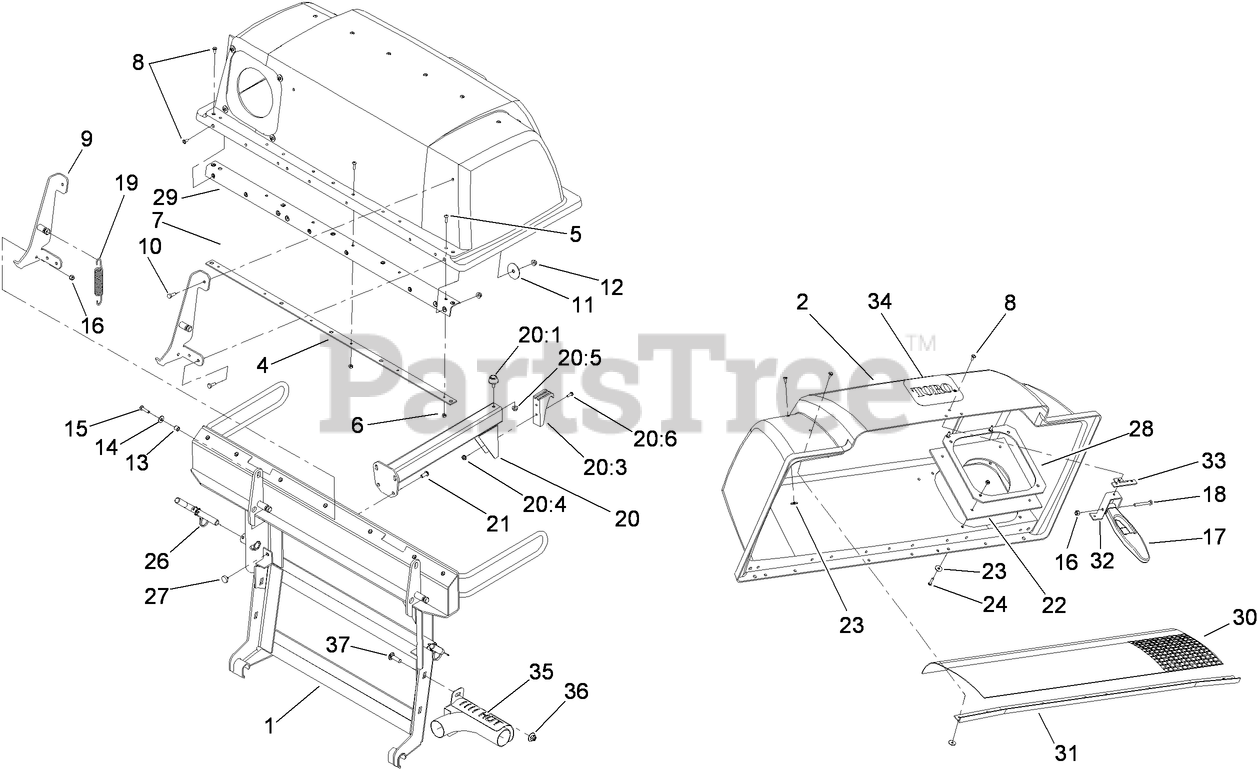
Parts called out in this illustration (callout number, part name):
1	FRAME-BAG, TWIN
2	HOOD ASM
4	PLATE-BACKING
5	SCREW-HEAD, TRUSS
6	NUT-LOCK, NI
8	RIVET-BLIND
9	HINGE ASM
10	SCREW-HH
11	WASHER
12	NUT-HF
13	SPACER
14	WASHER-FLAT
15	SCREW-HH
16	NUT-LOCK, NI
18	SCREW-HH
19	SPRING-EXTENSION
20	BAG SUPPORT ASM
20:1	BUMPER
20:4	NUT-HF
20:5	NUT-HF
20:6	SCREW-PPH
21	SCREW-HSBH
22	SEAL-CHUTE
23	WASHER-FLAT
24	SCREW-PPH
26	PIN-MOUNT, BAGGER
27	BUMPER
28	CLAMP-SEAL
29	STIFFENER-BAGGER, TOP
30	SCREEN-BAGGER
31	SUPPORT-SCREEN
32	ANCHOR-LATCH
33	REINFORCEMENT-LATCH
35	DIVERTER-EXHAUST
36	NUT-FLANGE, NI
37	SCREW-CARR
